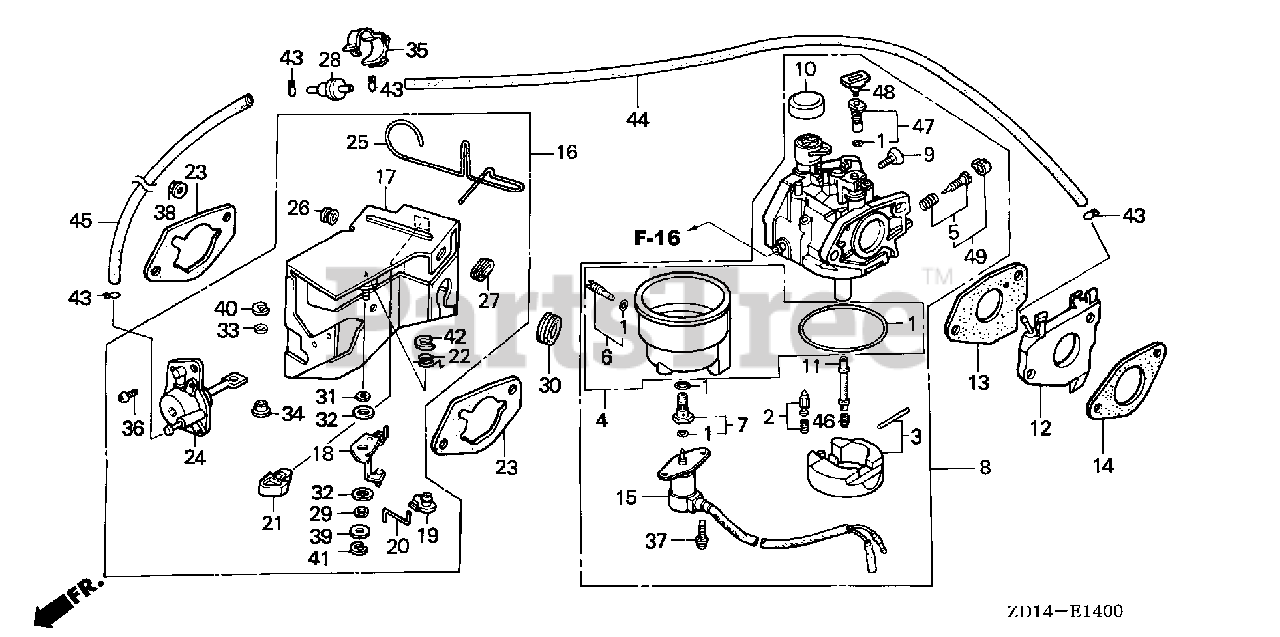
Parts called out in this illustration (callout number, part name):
1	GASKET SET
2	VALVE SET, FLOAT
4	CHAMBER SET, FLOAT
5	SCREW SET
6	SCREW SET, DRAIN
7	SCREW SET
8	CARBURETOR ASSY. (BE87H A)
8	CARBURETOR ASSY. (BE87H B)
8	CARBURETOR ASSY. (BE50A C)
8	CARBURETOR ASSY. (BE87A B/C)
8	CARBURETOR ASSY. (BE87A C)
9	SCREW, THROTTLE STOP
10	CAP, CHOKE DUST
11	NOZZLE, MAIN
12	INSULATOR, CARBURETOR
13	GASKET, CARBURETOR
14	GASKET, INSULATOR
15	VALVE ASSY., SOLENOID
16	STAY ASSY., MANUAL CHOKE
17	STAY, SOLENOID
18	LEVER, CHOKE
19	JOINT, ROD
20	ROD, CHOKE
21	STOPPER, CHOKE ROD
22	SPRING, MANUAL CHOKE
23	GASKET, AIR CLEANER
24	DIAPHRAGM ASSY.
25	ROD, CHOKE CONTROL
26	GROMMET, CHOKE ROD
27	GUIDE, CHOKE ROD
28	VALVE, DASHPOT CHECK
29	BUSH, ARM PIVOT
30	GROMMET, FENDER
31	WASHER, CHOKE LEVER
32	SEAL, CHOKE LEVER
33	WASHER, THRUST (2.7X8)
34	COLLAR, LEVER
35	CLIP, WIRE HARNESS
36	SCREW, PAN (5X12)
37	SCREW-WASHER (5X12)
38	NUT, FLANGE (6MM)
39	WASHER, PLAIN (5MM)
40	E-RING (2MM)
41	E-RING (4MM)
42	E-RING (7MM)
43	CLIP, TUBE (B7)
44	BULK HOSE, VACUUM (3.5X8000) (3.5X75)
45	BULK HOSE, VACUUM (3.5X8000) (3.5X130)
46	JET, MAIN (#98) Use up to Engine SN BE50A A.
46	JET, MAIN (#100) Use up to Engine SN BE50A A.
46	JET, MAIN (#102)
46	JET, MAIN (#98) Use from Engine SN BE87A A to BE87A A.
46	JET, MAIN (#100) Use from Engine SN BE87A A to BE87A A.
46	JET, MAIN (#102) Use from Engine SN BE87H A.
46	JET, MAIN (#105) Use from Engine SN BE87H A.
46	JET, MAIN (#108)
47	JET SET, PILOT (#45)
48	COLLAR, SETTING
49	SCREW SET
